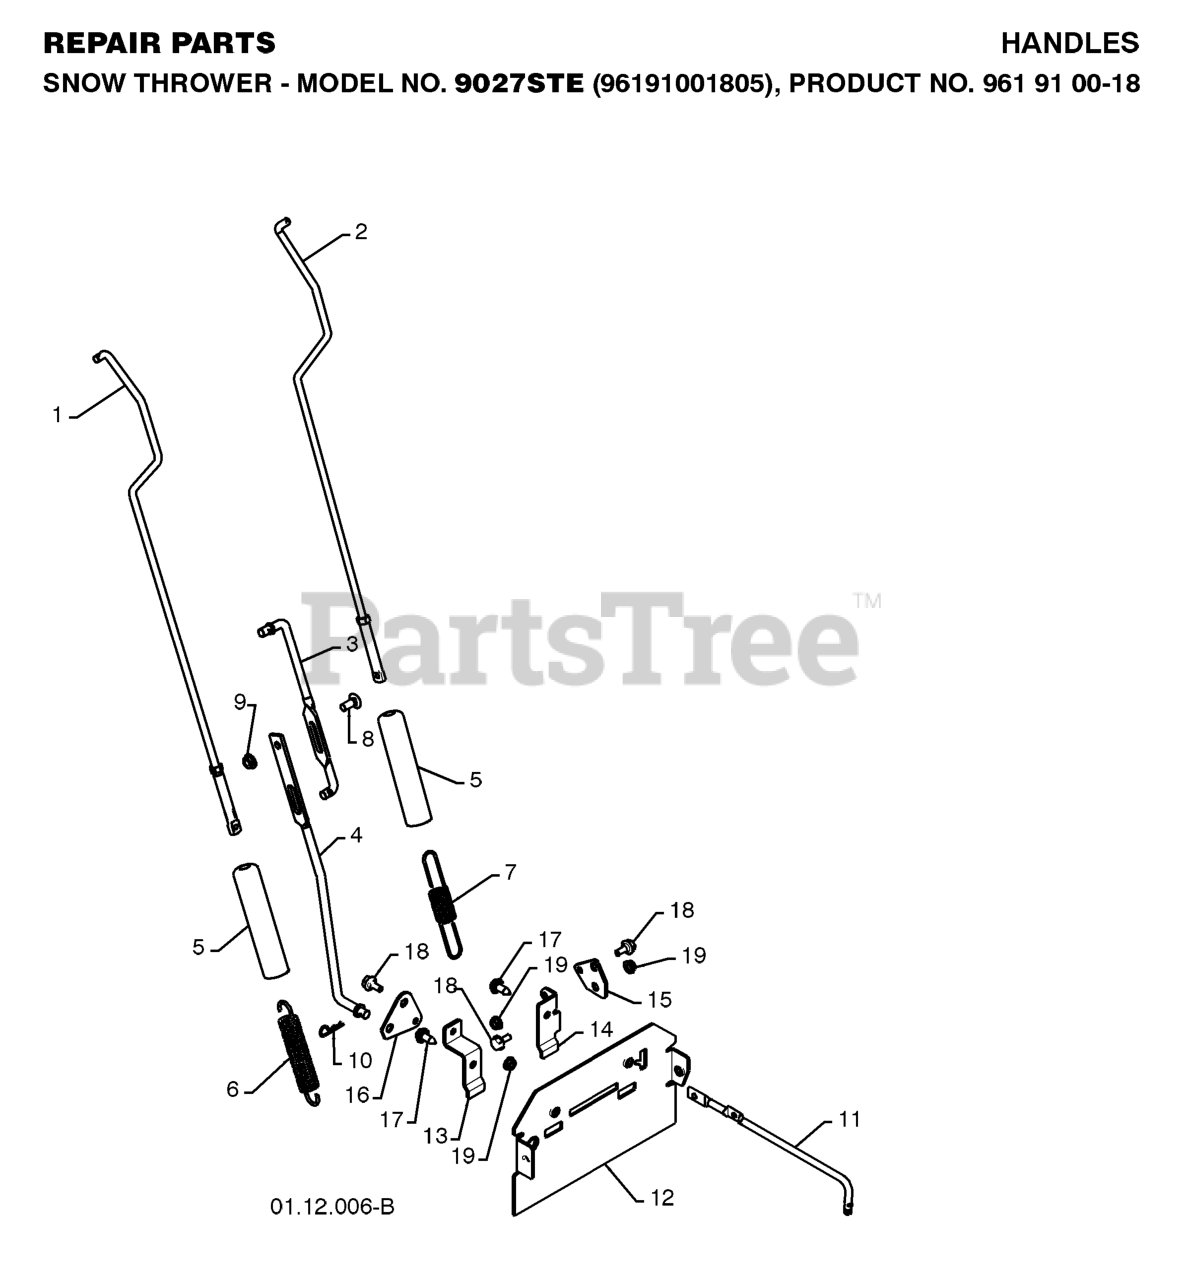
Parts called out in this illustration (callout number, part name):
1	ROD.ASM.IMPELLER
2	ROD.ASM.TRACTION
3	ROD, UPPER SPEED CONTROL
4	ROD, LOWER SPEED CONTROL.SNOW
5	SLEEVE, SPRING
6	SPRING, AUGER CONTROL
7	SPRING, TRACTION DRIVE
8	BOLT
9	NUT.FLANGE.5/16
10	SPRING RETAINER
11	ROD.CLUTCH.YELLOW.ZINC(VT)
12	PLATE.REAR.SNOW.PNT.ORANGE
13	BRACKET.SHIFTER.PLATE.BZP
14	BRACKET.CLUTCH.PLATE.BZP
15	PLATE.CLUTCH.BZP
16	PLATE.SHIFTER.BZP
17	SELF-TAPPING SCREW 5/16-18X3/4
18	BOLT.SHOULDER.3/X.25
19	NUT.HEX.FLANGE.1/4
